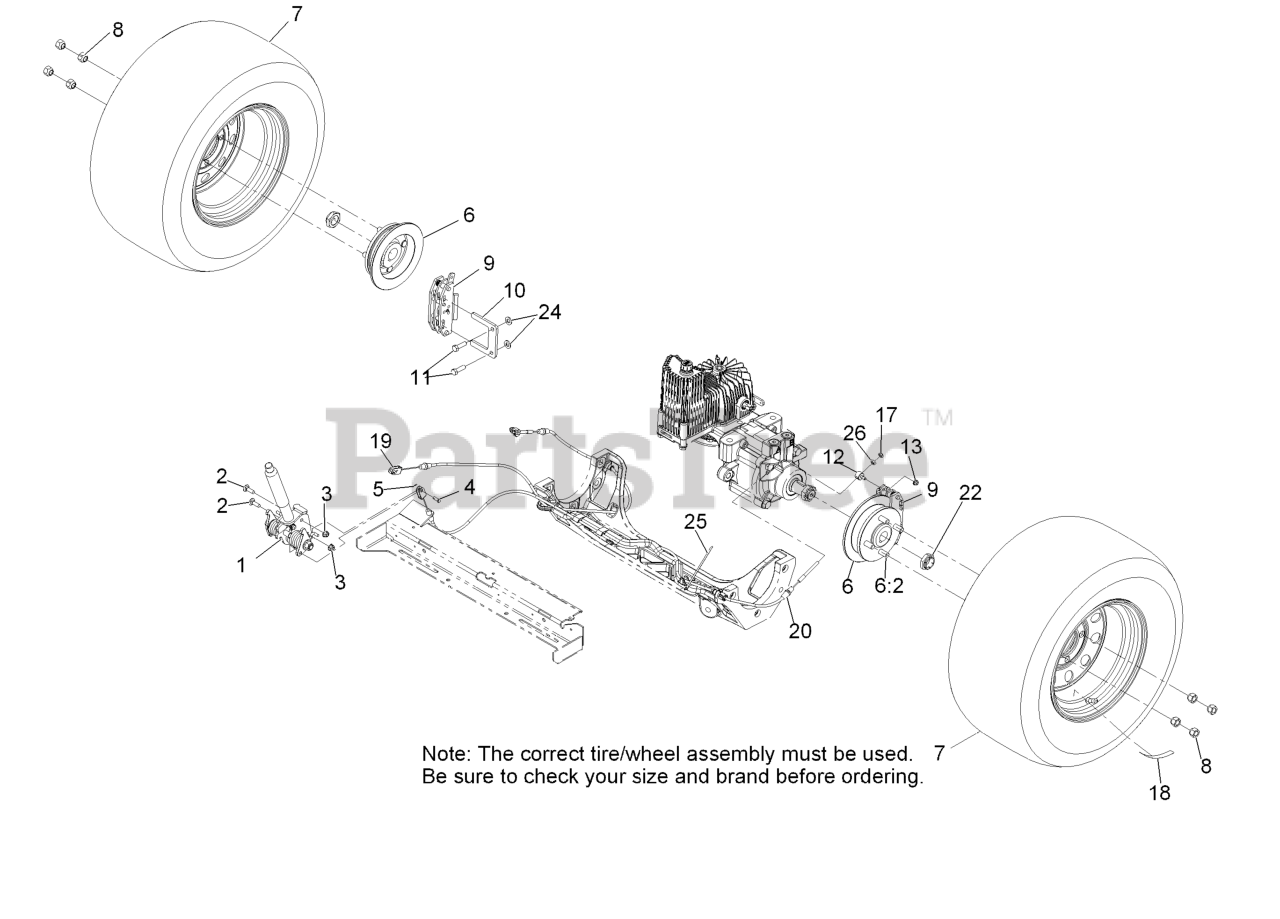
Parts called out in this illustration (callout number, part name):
1	BRAKE HANDLE ASM
2	BOLT-CARR
3	NUT-HF, NI
4	PIN-CLEVIS
5	PIN-COTTER
6	WHEEL HUB ASM
6:2	STUD-WHEEL
7	WHEEL AND TIRE ASM
7	ASM-WHEEL AND TIRE
8	NUT-LUG
9	CALIPER-BRAKE
10	PLATE-MOUNT, BRAKE
11	SCREW-LOCK, PATCH
17	NUT-LOCK, NI
22	LOCKNUT
24	WASHER-FLAT
25	TIE-CABLE
26	NUT-HEX
